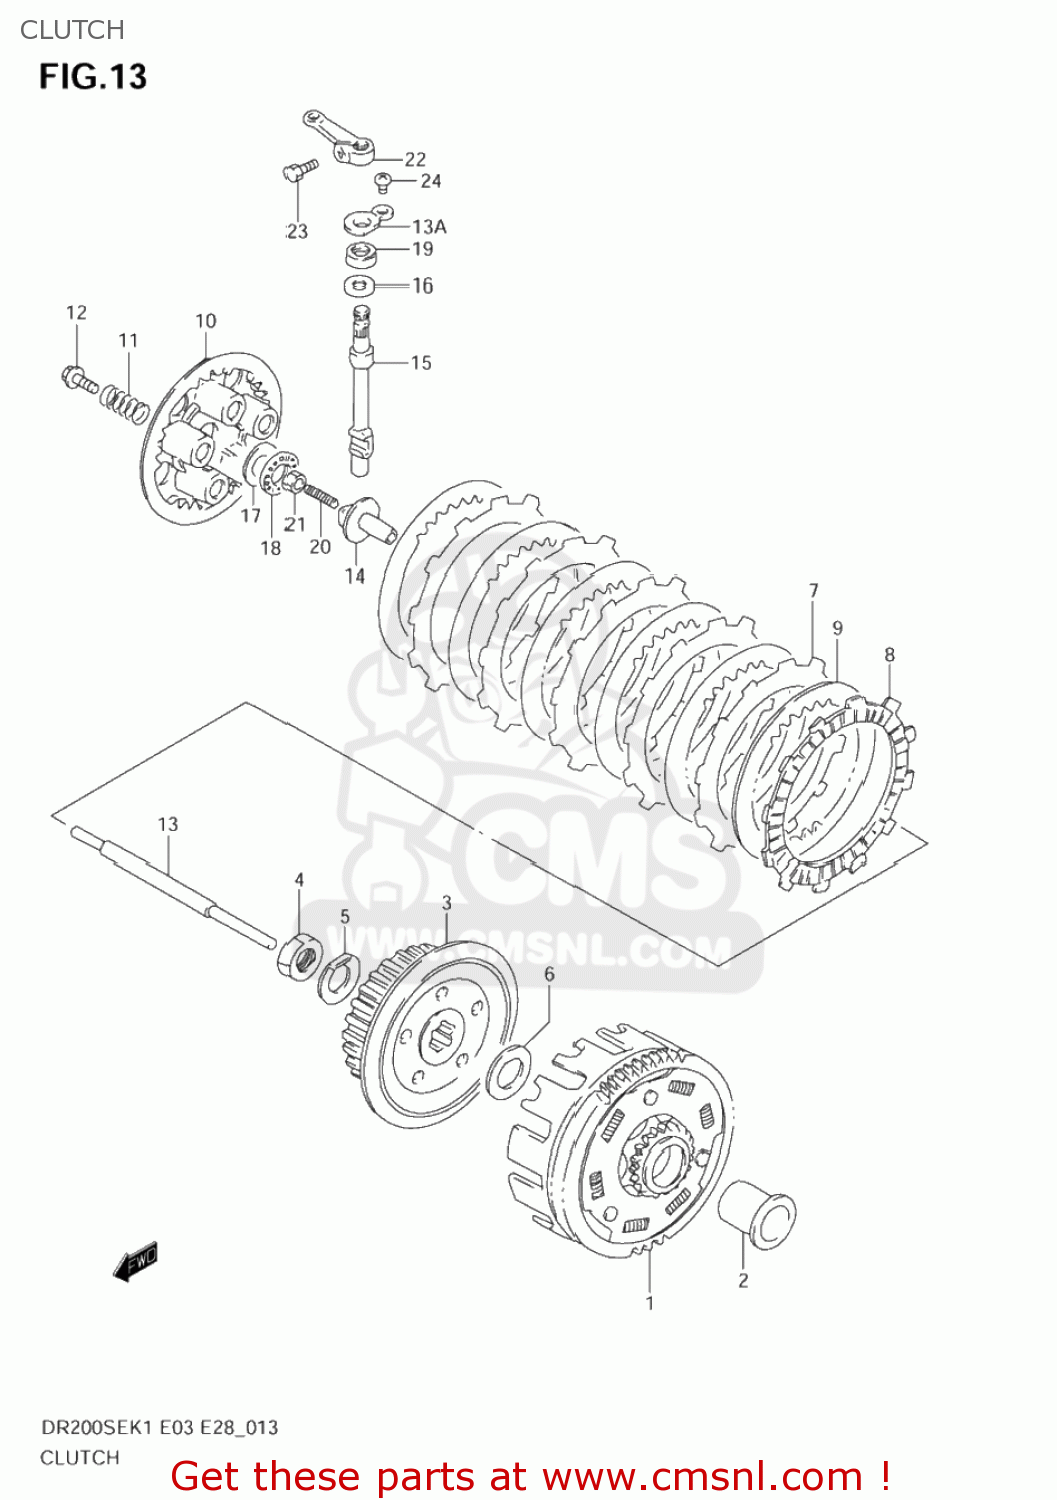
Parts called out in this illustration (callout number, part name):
1	GEAR ASSY,PRI DRIVEN
2	SPACER,PRIMARY DRIVEN GEAR
3	HUB,CLUTCH SLEEVE
4	NUT
5	WASHER
6	WASHER
7	PLATE,CLUTCH DRIVE (NAS)
8	PLATE,CLUTCH DRIVE(T:3.0) (NAS)
9	PLATE,DRIVEN(T:1.4)
10	PLATE,CLUTCH PRESSURE
11	SPRING
12	BOLT(5X16)
13	ROD,CLUTCH PUSH
13A	RETAINER,CL RLSE OIL SEAL
14	PIECE,CLUTCH PUSH
15	CAMSHAFT,CLUTCH RELEASE
16	SHIM(10X20X1)
17	WASHER(15.5X28X1)
18	BEARING(15X28X2)
19	SEAL,OIL(10X20X6)
20	SCREW(6X25)
21	NUT
22	ARM,CLUTCH RELEASE
23	BOLT
24	SCREW 6X10
